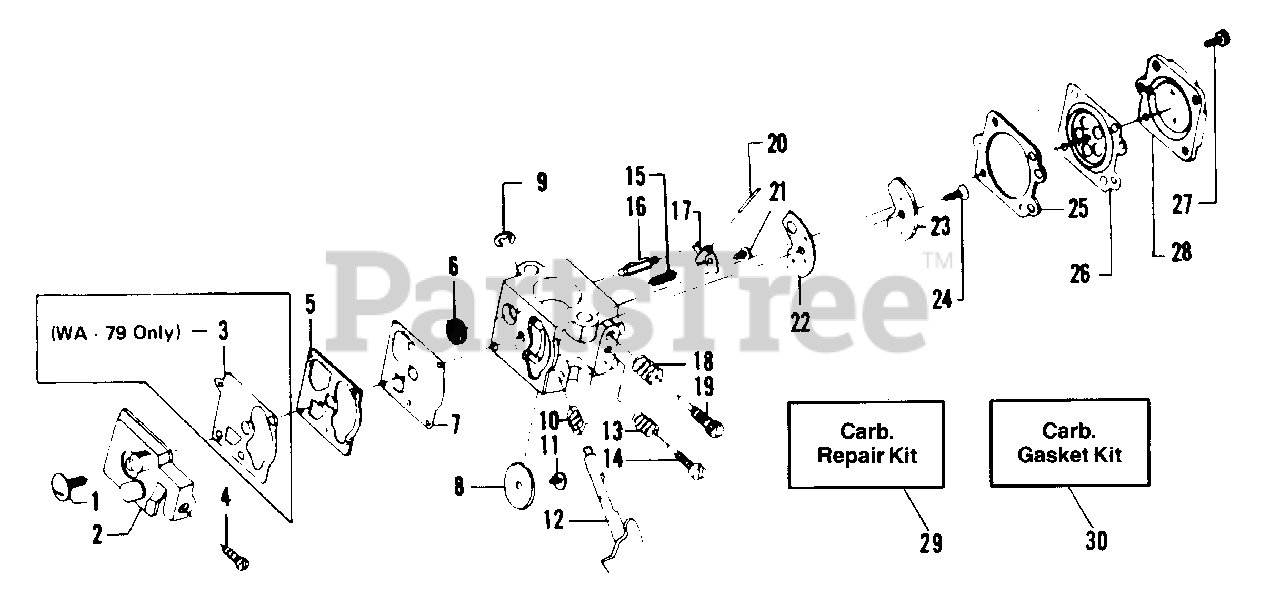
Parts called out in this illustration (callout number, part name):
1	Screw - Pump Cover
2	Pump Cover Ass'y (Inc.4) WA-79
2	Pump Cover Ass'y (Inc.4) WA-149 (#35183)
3	Diaphragm - Pump WA-79 Only
4	Screw - Idle Adjustment
5	Gasket - Pump WA-79
6	Screen - Inlet
7	Diaphragm - Pump WA-79
7	Diaphragm - Pump WA-149 (#35183)
8	Valve - Throttle
9	Clip - Throttle Shaft
10	Spring - Throttle Return
11	Screw - Throttle Valve
12	Shaft Assembly - Throttle
13	Spring - Idle Needle
14	Needle - Idle
15	Spring - Metering Lever
16	Valve - Inlet Needle
17	Lever - Metering
18	Spring - Hi Speed Needle
19	Needle - Hi Speed
20	Pin - Metering Lever
21	Screw - Metering Lever Pin
22	Gasket - Circuit Plate
23	Plate - Circuit
24	Screw - Circuit Plate
25	Gasket -Metering Diaphragm
26	Diaphragm Ass'y - Metering
27	Screw - Assembly - Metering Cover & Throttle Shaft Clip
28	Cover - Metering Diaphragm
29	Kit - Kwik Repair WA-79
29	Kit - Kwik Repair WA-149
30	Kit - Gasket/Diaphragm WA-79
30	Kit - Gasket/Diaphragm WA-149 (#35183)
